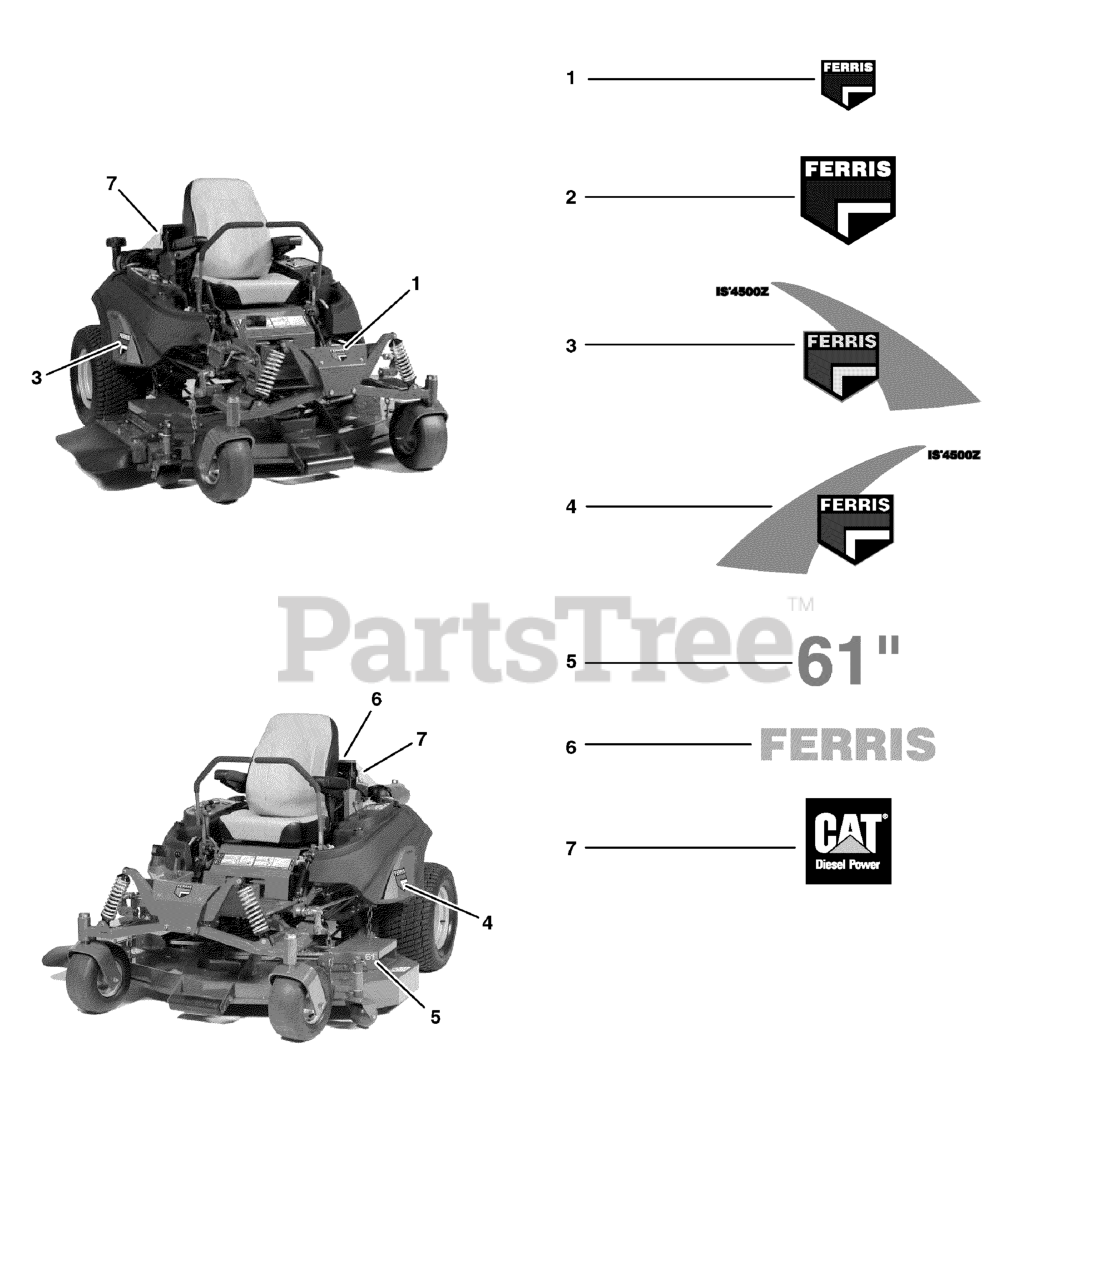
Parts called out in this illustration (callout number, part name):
1	DECAL, Ferris Logo, 3-1/2"
2	DECAL, Ferris Logo, 6-3/8"
3	DECAL, Tank Badge, LH
4	DECAL, Tank Badge, RH
5	DECAL, 61"
6	DECAL, Ferris Text
7	DECAL, CAT Diesel
